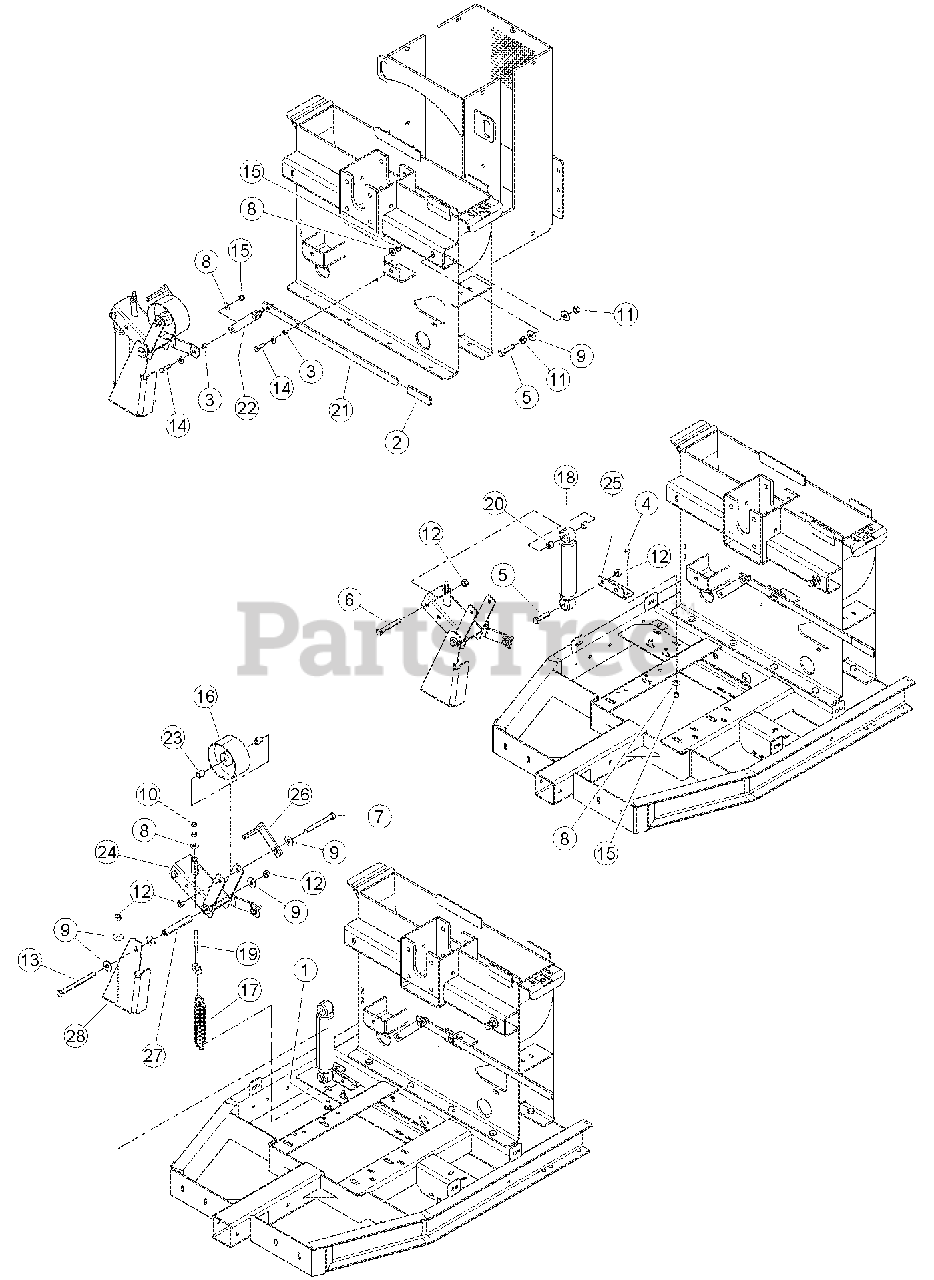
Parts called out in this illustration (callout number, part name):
1	BOLT, 1/2 X 1 CRG GR5 ZP
2	GRIP, CLUTCH HANDLE
3	BUSHING, 3/8 X 1/2 SLEEVE LUBE
4	BOLT, 3/8 X 1 HEX HD GR5 ZP
5	BOLT, 1/2 X 2 HEX HD GR5 ZP
6	BOLT, 1/2 X 3-1/2 HEX HD GR5 ZP
7	BOLT, 1/2 X 4-1/2 HEX HD GR5 NC ZP
8	WASHER, 3/8 FLAT ZP
9	WASHER, 1/2 FLAT ZP
10	NUT, 3/8 HEX NC ZP
11	NUT, 1/2 HEX NC ZP
12	NUT, 1/2 CENTERLOCK GRB ZP
13	BOLT, 1/2 X 6 HEX HD GR5 ZP
14	BOLT, 3/8 X 1-1/4 HEX HD GR5 ZP
15	NUT, 3/8 NE NYLOCK ZP
16	PULLEY, IDLER 5" X 2.50"
17	SPRING, 7-3/4" EXTENSION
18	ABSORBER, IDLER SHOCK
19	EYEBOLT, 3/8"X 5"LG 4-1/4 THD ZP
20	SPACER, 0.75 X 0.620
21	LEVER, CLUTCH ENGAGEMENT
22	LINK, ENGAGEMENT ARM
23	SPACER, IDLER SHEAVE
24	WELDMENT, IDLER ARM
25	BRACKET, SPRING ANCHOR
26	WELDMENT, BELT PIN
27	BUSHING, IDLER PIVOT
28	BRACE, IDLER
